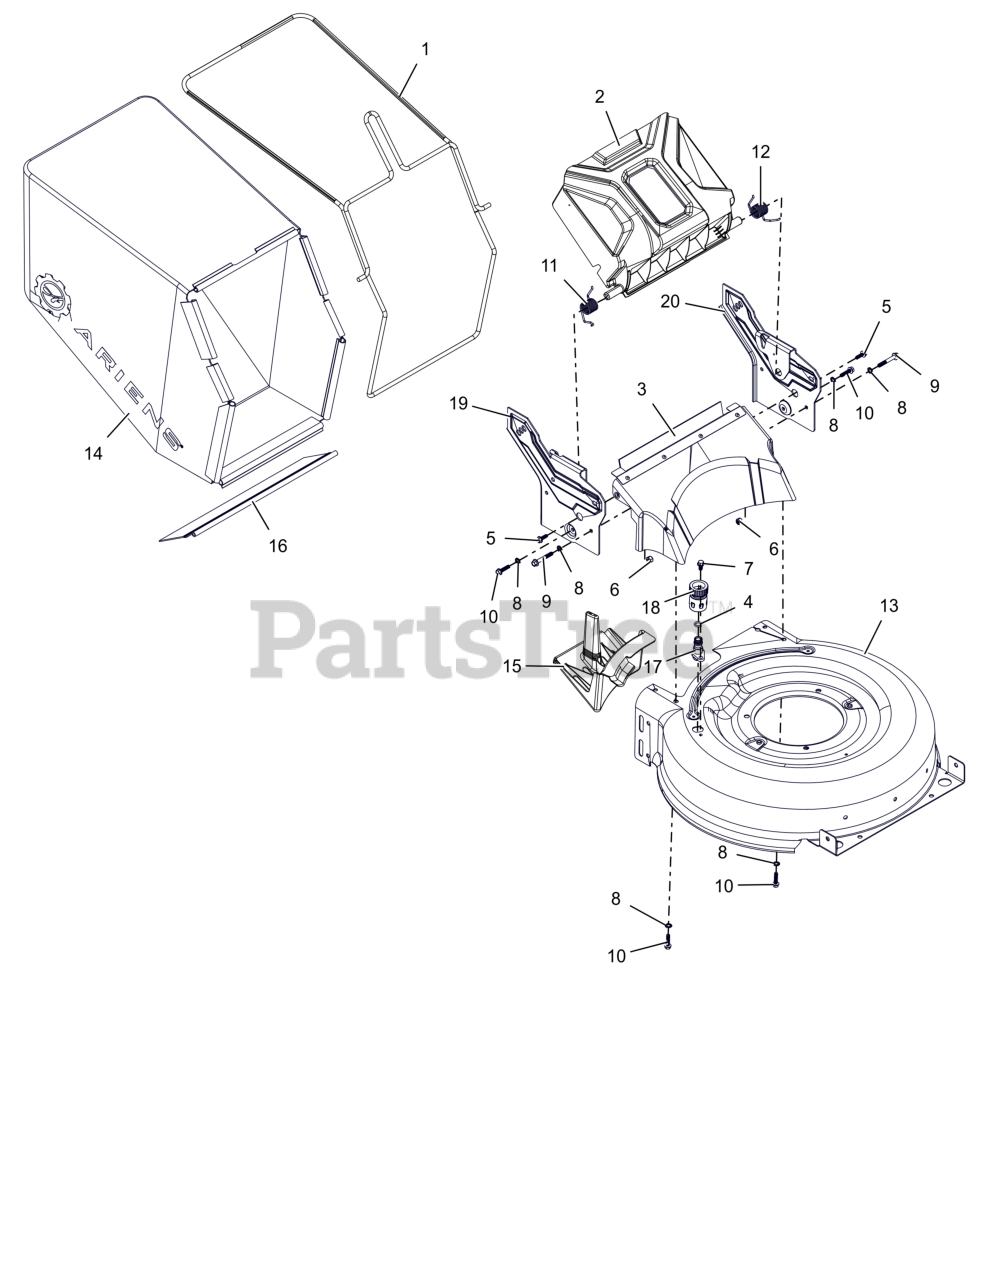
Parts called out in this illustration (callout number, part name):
1	WLDMT, BAG FRAME (ORANGE)
2	ASM, REAR DOOR
3	ASM, REAR COVER-FWD
4	O-RING, OD .625 ID .425
5	SCR, HI-LO HWH 1/4-15 X .750
6	NUT, NYLOC 1/4-20
7	SCR, 1/4-20X.500, THREAD FORMING
8	WSHR-LK-EXT, .256X.510X.028
9	BLT, HEX 1/4-20 X 1.75 GR5
10	SCR, HI-LO HWH 1/4-15 X 1.00
11	SPRG, TORSION - DOOR LH
12	SPRG, TORSION - DOOR RH
13	DECK, RWD -21 (WO PORT) (ORANGE)
14	BAG, ARIENS
15	PLUG, MULCH
16	GUARD, REAR DECK
17	ADAPTOR, DECK WASH OUT
18	CONNECTOR, QUICK DISCONNECT
19	BRKT, RH SIDE (BLACK)
20	BRKT, LH SIDE (BLACK)
